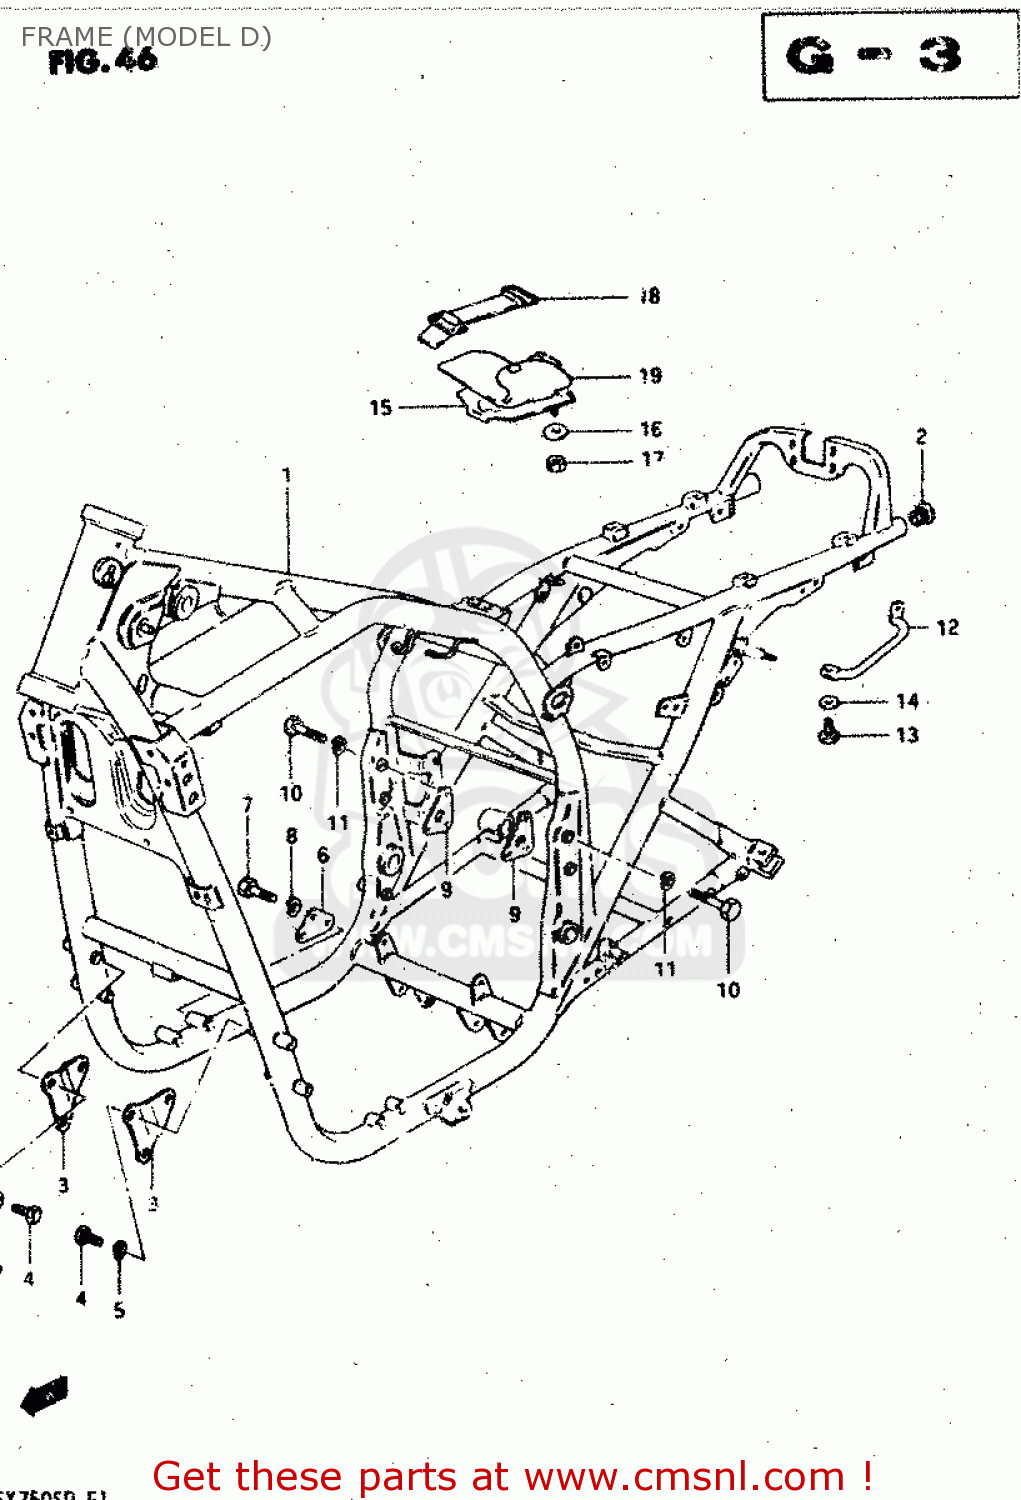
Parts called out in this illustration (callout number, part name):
1	FRAME (SILVER)
2	CAP(OD:26)
3	PLATE,ENG MTG NO.1
4	BOLT(8X65)
5	LOCK WASHER
6	PLATE,ENG MTG NO.2
7	BOLT 8X16
8	LOCK WASHER
9	PLATE,ENG MTG NO.4
10	BOLT
11	LOCK WASHER
12	GRIP,STAND
13	BOLT
14	WASHER
15	HOLDER,TOOL
16	WASHER(6.5X30X1.6)
17	NUT
18	BAND
19	TOOL SET
